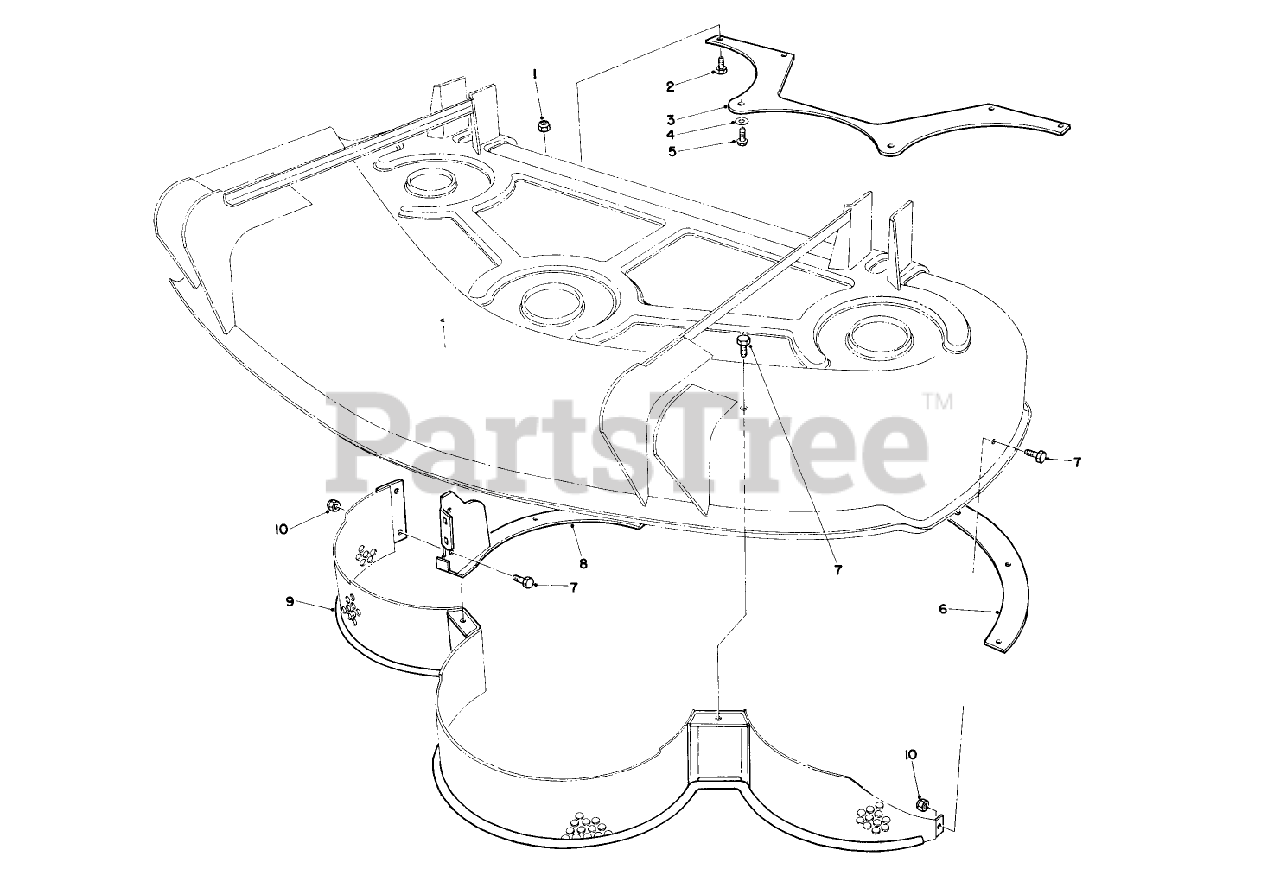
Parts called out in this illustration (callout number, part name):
1	NUT-LOCK, NI
2	SCREW-HH
3	Baffle Bagging
4	WASHER-FLAT
5	SCREW-HHFTF
6	RING - LH BAGGING R
7	SCREW-HH
8	Ring-Bagging RH
9	Screen
10	NUT-LOCK, NI
